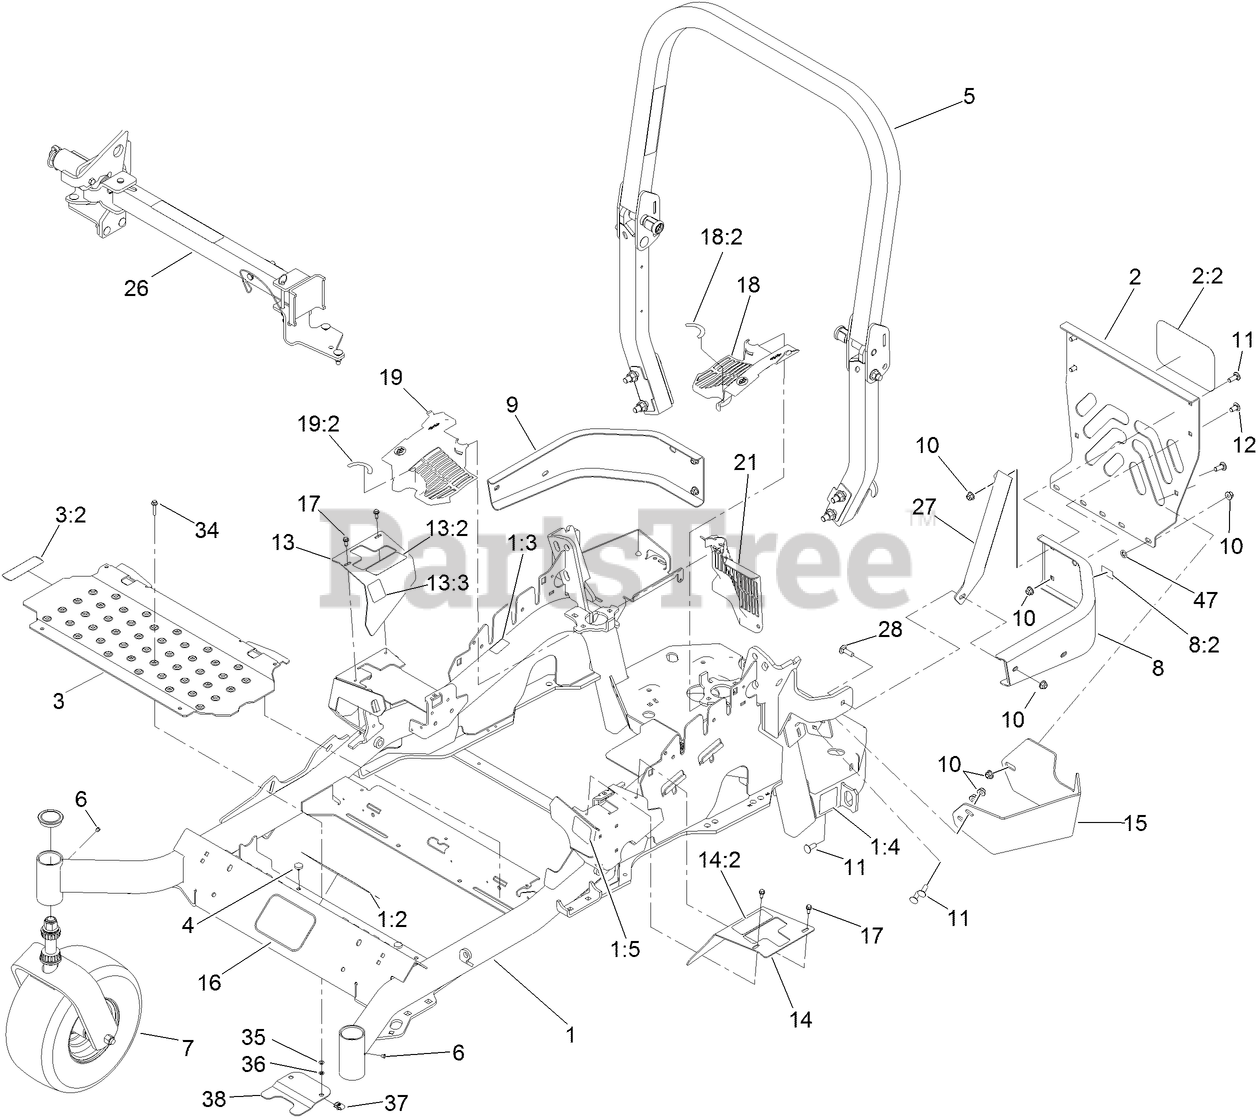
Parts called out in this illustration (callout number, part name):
1	MAIN FRAME ASM
1:2	DECAL-DANGER SLOPE W/ROPS
1:3	DECAL-WARNING
1:4	DECAL-HAZARD, PINCHED FINGER
1:5	DECAL-FUEL FILL, CE
2	REAR GUARD ASM
2:2	DECAL
3	FLOORPAN ASM
3:2	DECAL-MISSING, COVER
4	BUMPER
5	ROPS ASM
7	Caster Wheel ASM
8	LH REAR BUMPER ASM
8:2	DECAL-WARNING
9	BUMPER-RH
10	NUT-HF, NI
11	SCREW-CARR
12	SCREW-CARR
13	RH MOTION CONTROL COVER ASM
13:2	DECAL-CONTROL, MOTION
13:3	DECAL-PARK BRAKE, CE
14	LH MOTION CONTROL COVER ASM
14:2	DECAL-CONTROL, MOTION
15	GUARD-MUFFLER
16	DECAL
17	SCREW-HWH
18	LH HYDRO GUARD ASM
18:2	DECAL-HYDRO OIL
19	RH HYDRO GUARD ASM
19:2	DECAL-HYDRO OIL
21	GUARD-HYDRO, REAR (RH)
26	Z STAND ASM
28	BOLT-CARR
34	SCREW-HHF
35	WASHER-FLAT
36	NUT-RETAINER
38	ADAPTER-CAPTIVE
47	NUT-PUSH
